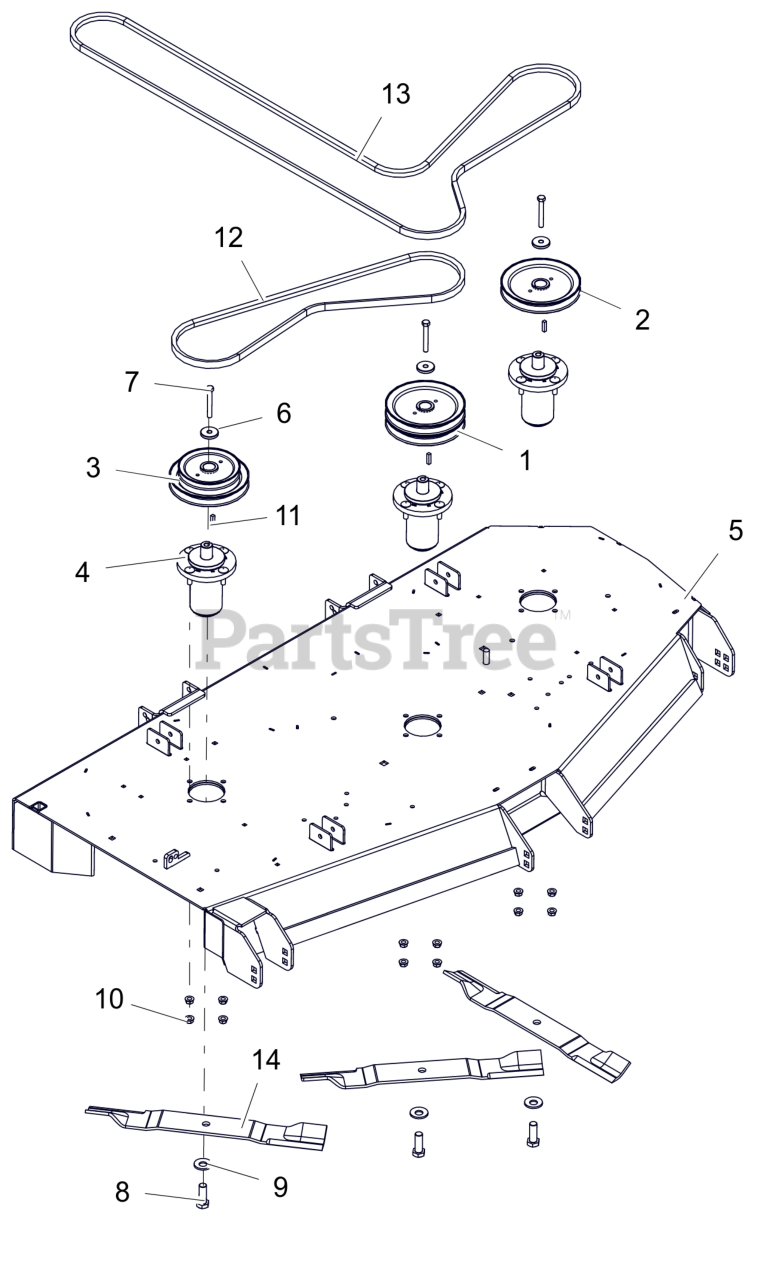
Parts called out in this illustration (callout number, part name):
1	PULLEY, DOUBLE 1.000 ID X 6.750 OD
2	PULLEY, V-1" ID X 6.75 OD
3	PULLEY, DBL-1"IDX6.75"&5.25"OD
4	ASM, MAINT FREE ALUM SPINDLE
5	WLDMT, 60" SIDE DISCH DECK (RED) W/ SAFETY DECALS
6	RETAINER, SHEAVE
7	BLT, HEX .38-16X2.75 G8 ZCC
8	BLT, HEX .62-18X1.75 G8 ZCC
9	WSHR-BLVL .669X1.535X.138
10	NUT-LK-CTR-FLG .375-16 GF ZCC
11	KEY, SQ .25X.25X1.00 RC 40-50
12	V-BELT, B-COGGED
13	BELT, B-SECTION EPDM RAW EDGE
14	BLADE, MOWER (20.50")
